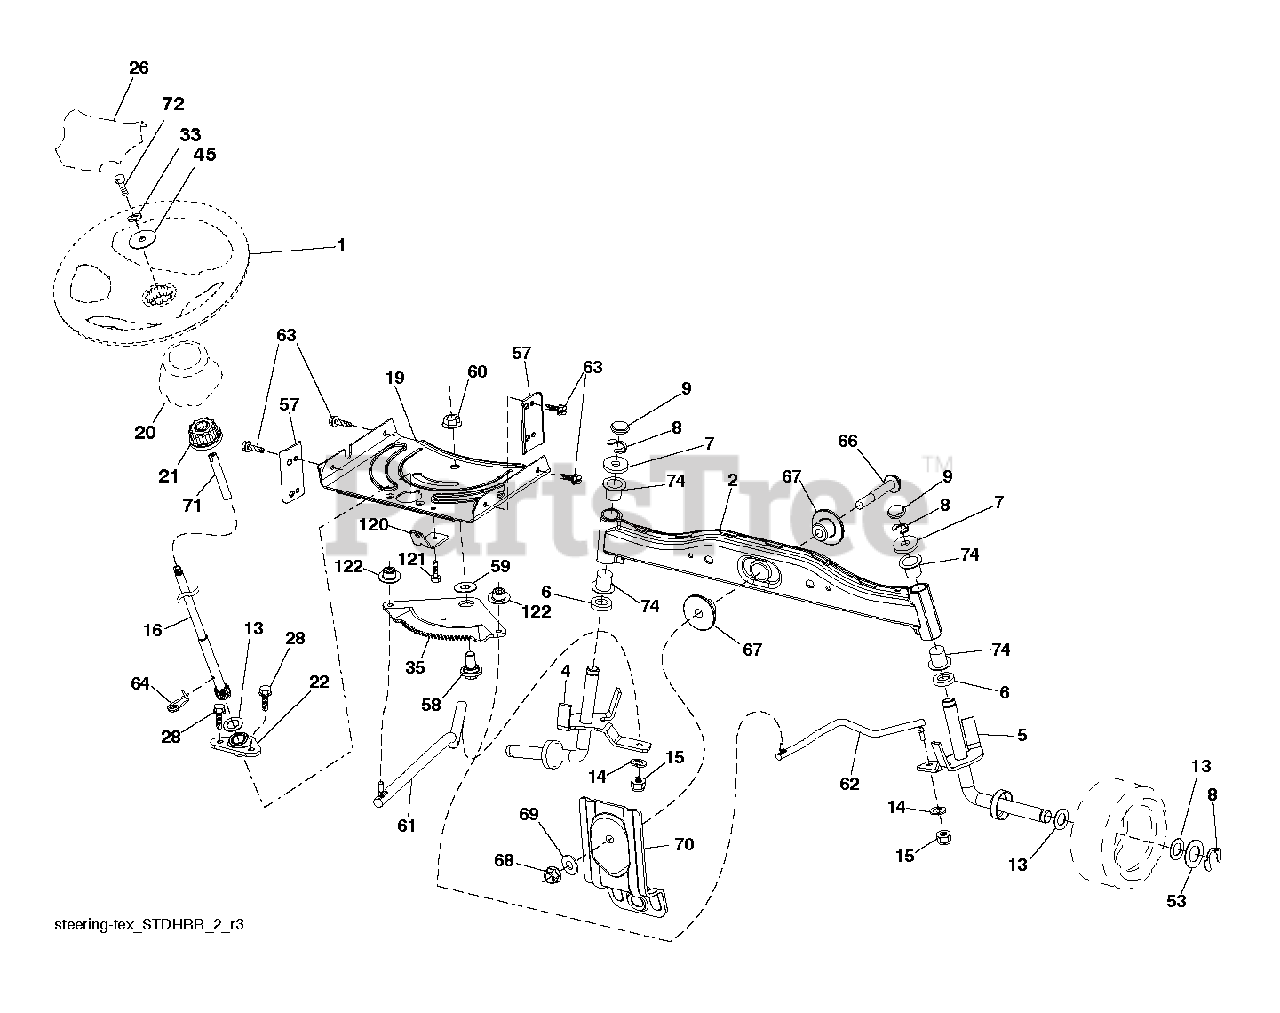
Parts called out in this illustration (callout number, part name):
1	WHEEL.STEERING.HARD.RIM.BLAC
2	AXLE HALF ASM-WELDED
4	SPINDLE.WELDED.LH.15"TEX
5	SPINDLE.WELDED.RH.15"T
8	RING CLIP
9	CAP.SPINDLE.BLACK
14	WASHER, LOCK 3/8
15	NUT CROWNLOCK 3/8-24
16	SHAFT.STEER.3/4.NON-PLATED.TEX
19	PLATE.STEER.DDL.NLT/NG
20	BOOT STEERING BLACK
21	ADAPTER, WHEEL STNG..
22	STEERING.SUPT.LOWER.
26	INSERT, WHEEL STEERING
28	SCREW, 3/8-16X3/4
33	LOCKWASHER
35	GEAR.SECTOR.PLATE.DDL.
45	WASHER.11/32
53	WASHER.HARDENED
57	BRACKET.UPSTOP.TEX
58	BOLT.SHOULDER.SECTOR.P
59	WASHER.THURST.SECTOR.S
60	NUT FLANGE LOCK 5/8-11
61	DRAGLINK.LH.BALLSTUD.D
62	DRAGLINK.RH.BALLSTUD.D
63	SCREW
64	RETAINER.CLIP.SPRING.S
66	BOLT HEX FGHD 7/16-14 X 3 SERR
67	BUSHING.PM.FRONT AXLE
68	NUT.LOCK.FLANGE.7/16
69	WASHER.1.5X.505X.118
70	BRKT.DECK.SUSPENSION.F
71	SHAFT.EXTEN.STRG.SPLINE
72	BOLT 5/16-18 X 4 W/PATCH
74	Steering Column Bearing
120	BRKT.LOCATOR.CBL.BRAKE.VARIATO
121	SCREW LT
122	CAP.GEAR.SECTOR.TEX
